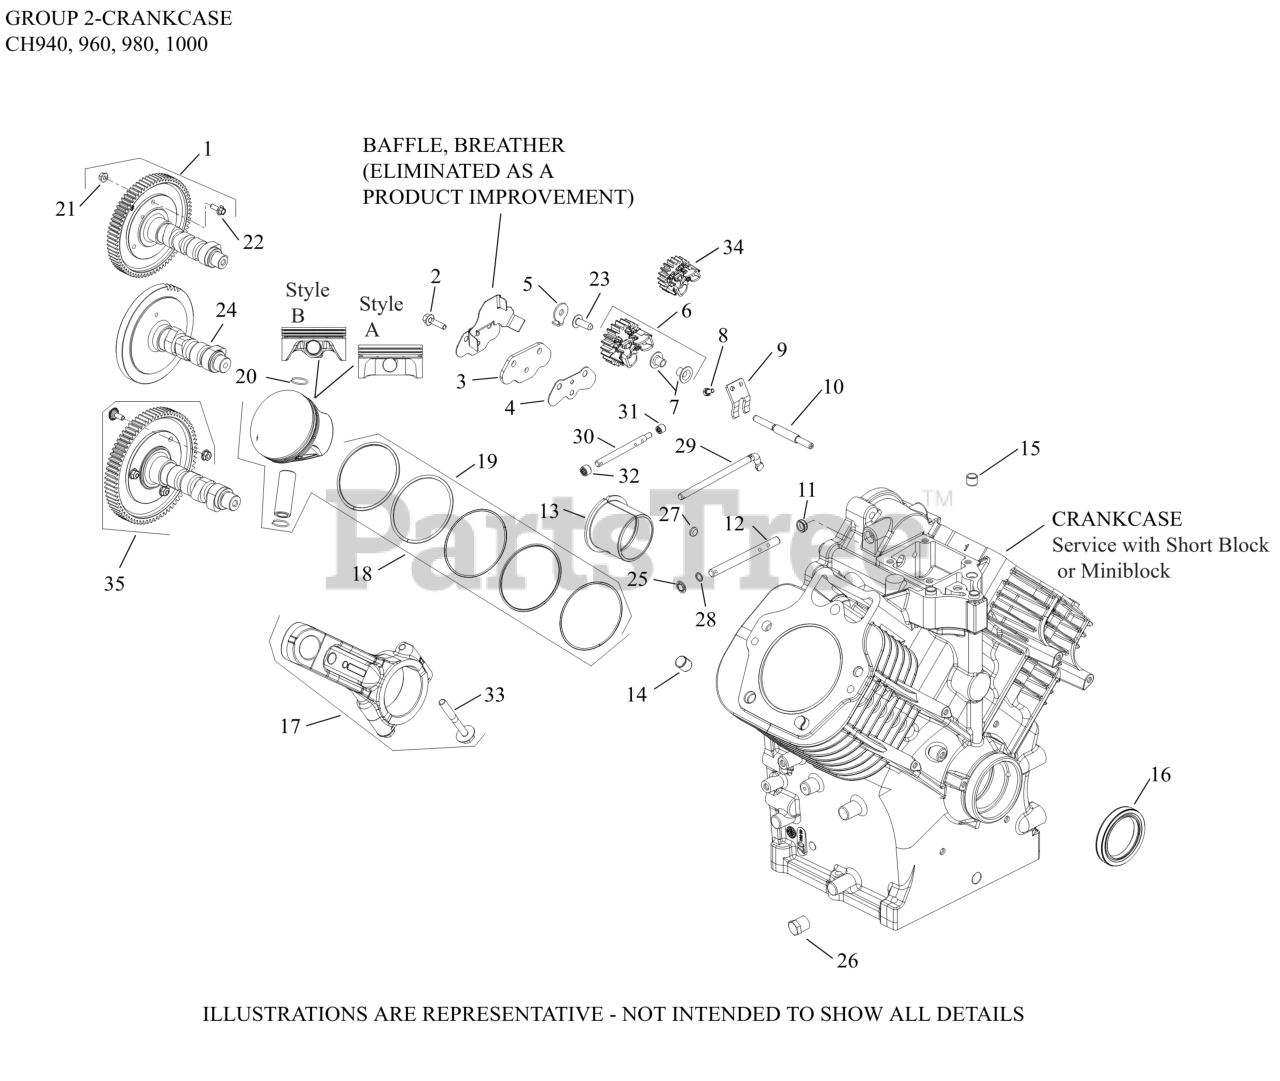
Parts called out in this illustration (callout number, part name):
2	SCREW, HVY FLG M5X0.8X20
3	KIT, COVER, LIFTER FEED
4	GASKET, LIFTER FEED COVER
5	TAB, LOCKING
6	KIT, GOVR GEAR ASSY-(#2531009S)
7	PIN, GOVERNOR REGULATING
8	SCREW, HEX HEAD
9	YOKE, GOVERNOR
10	SHAFT, GOVERNOR GEAR
11	SEAL, GOVERNOR CROSS SHAFT
12	SHAFT, GOVERNOR CROSS
14	PIN, LOCATING
16	SEAL, OIL-USE 62 032 21-S
16	SEAL, OIL-(#2503217S)
17	CONNECTING ROD ASSEMBLY
18	KIT, PISTON ASSY (STD)-USE 62 874 17-S
18	KIT, PISTON ASSEMBLY (.25)
18	KIT, PISTON ASSEMBLY (.50)
18	KIT, PISTON (STD)
18	KIT, PISTON (0.25 OS)
18	KIT, PISTON (0.50 OS)
19	RINGS, .25 O/S-USE 24 108 16-S
19	RING SET (STD)-(#DSC)
19	RING SET (.25)
19	RING, SET PISTON (STD)
20	RETAINER, PISTON PIN
21	NUT, FLG M6X1.0
22	SCREW,HEX FLNGE
35	KIT, CAMSHAFT - USE 62 010 11-S
